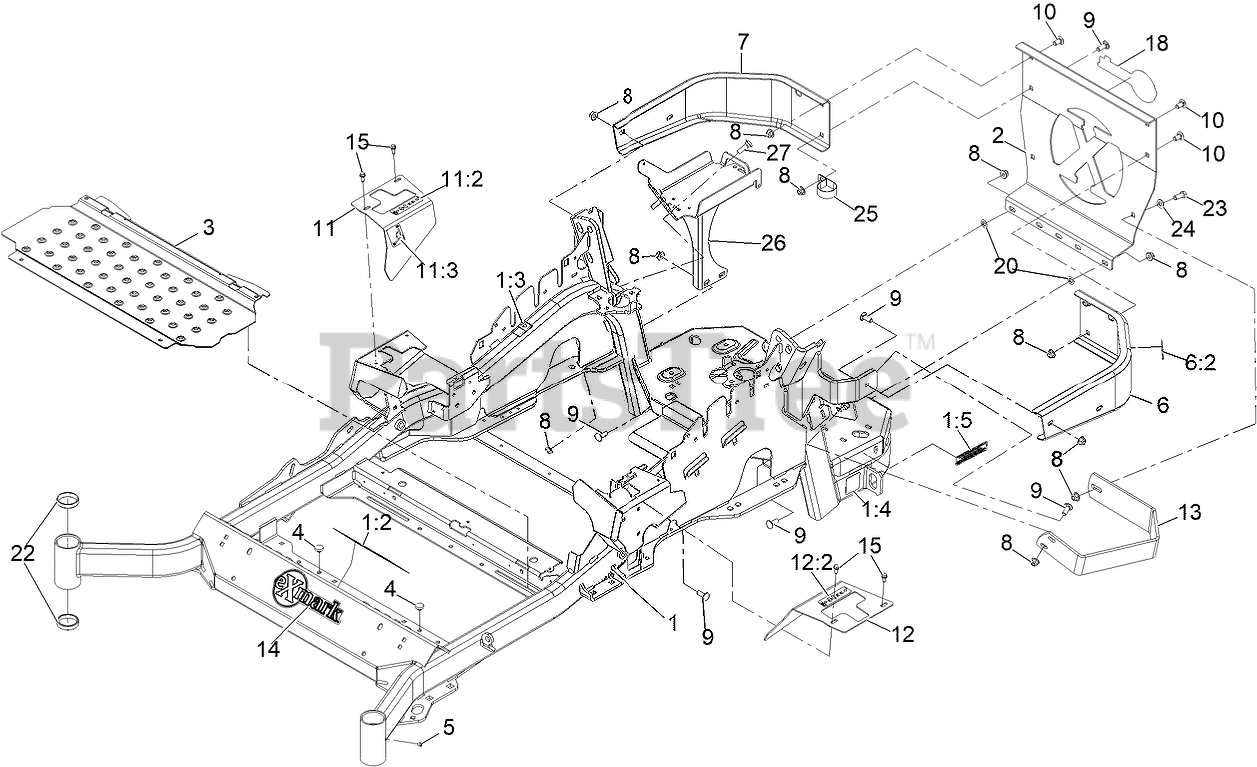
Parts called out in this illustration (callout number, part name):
1	MAINFRAME SERVICE ASM - 60
1:2	DECAL-DANGER
1:3	DECAL-WARNING
1:4	DECAL-HAZARD, PINCHED FINGER
1:5	DECAL-ARRESTOR, SPARK
2	PLATE,REAR GUARD
6	LH BUMPER ASM
6:2	DECAL-WARNING
7	BUMPER-RH
8	NUT-HF, NI
9	SCREW-CARR
10	SCREW-CARR
11	RH MOTION CONTROL COVER ASM
11:2	DECAL-CONTROL, MOTION
11:3	DECAL-PARK BRAKE, CE
12	LH MOTION CONTROL COVER ASM
12:2	DECAL-CONTROL, MOTION
13	GUARD-MUFFLER
14	DECAL-EXMARK
15	SCREW-HWH
18	DECAL, EXMARK LOGO
20	NUT-PUSH
22	CUP-BEARING
23	SCREW-HH
24	WASHER-FLAT
25	CLAMP-R
26	BATTERY MOUNT ASM
27	BOLT-CARR
